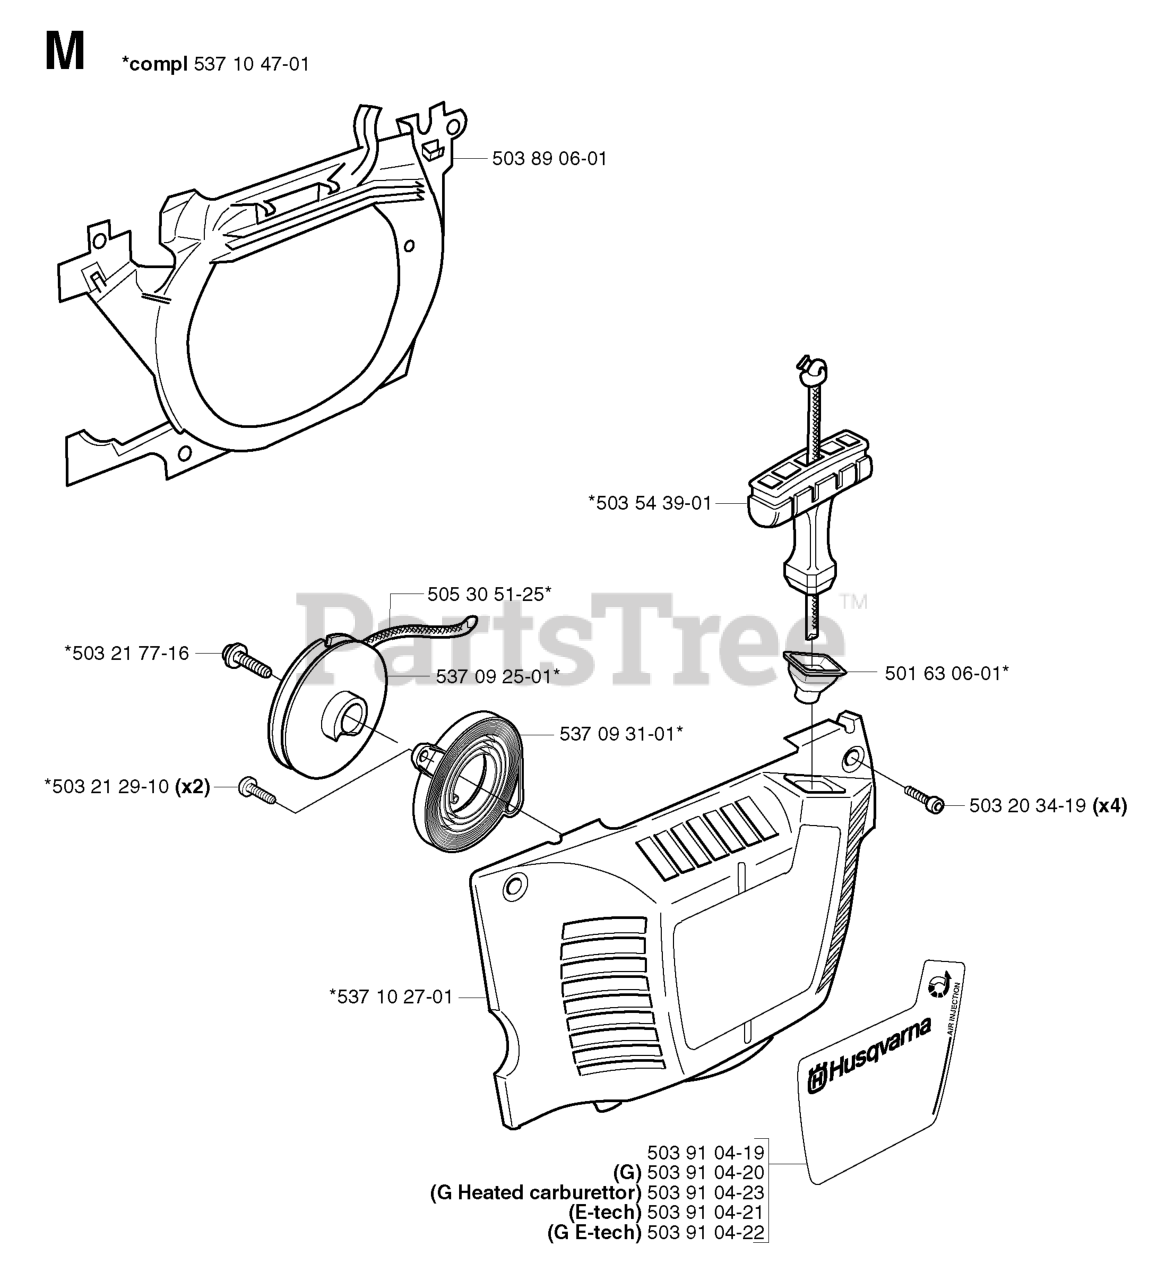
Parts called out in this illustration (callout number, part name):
3	APPLIQUE.SUBASM.GT.HUSQ.II
5	UPPER.GT2.SVC.MINDING.C-O.M;H
14	HOOD.ASM.HUSQVARNA.GT.TEX.ORAN
15	LENS.HEADLIGHT.LH.GTII.2011
18	GRILLE.SUBSTRATE.2011.
25	LENS.HEADLIGHT.RH.GTII.2011
34	PLATE.ENGINE.WELDED.CHASSIS
36	SCREW 5/16"
37	FENDER.TLT.PDL.CNTRL.W/CPH.ORG
52	LOCKNUT
68	Screw 5/16-18 x 1/2 Hex, Self Tapping 5/16-18 x 1/2
125	CLIP.FUEL.LINE
130	SCREW.#10 X 0.750.BOS
137	BUMPER DASH
138	HOLDER.CUP.LT.GREY
146	BOLT.RDHD.SHT.SQNK.3/8-16X5/8
150	AIR.DUCT.GTV2(2.54"RING HEIGHT
151	BRACKET.PIVOT.HOOD.GT.HUSQ.II
152	SHIELD.BROWNING.PNT.GT.V2
159	SCREW, 3/8-16X3/4
162	SCREW.HI-LO.CONSOLE
175	PLATE.CROSSMEMBER.HUSQ
176	SCREW.#10-24X5/8.RN.QU
177	BUSHING STEERING
180	CHASSIS
181	BUSHING.MNT.FEND.CRGO.TEX.49
182	DASH LOWER.HUSQ.PRED NO CRUISE
183	BOLT.5/16-18X1-1/4 FULL THD
189	SCREW
191	INSERT.REFLECTIVE.RH.HUSQ.GTII
194	NUT LOCK HEX FLANGE 5/16-18
195	PLUG.HOLE.DASH.LOWER.12V.BLK
196	DECKLFT.CONSOL FULL ASSM GREY
202	VENT.SIDE.RH.GT.HUSQ.II.
203	VENT.SIDE.LH.GT.HUSQ.II.498
204	VENT.TOP.HUSQ.GT2
205	SIDE.TRIM.RH.GT.HUSQ.II
206	SIDE.TRIM.LH.GT.HUSQ.II.GRAY
207	BEZEL LIGHT.RH.GT.II.MYLAR
208	BEZEL LIGHT.LH.GT.II.MYLAR
213	BOLT
214	CLIP.RETAINER.TINNER.
217	ROD.PIVOT.HOOD
218	X-PIECE.HOOD.STOP.NON/
228	STUD.FASTNER.W/ANTI-ROTATE
235	SPACER FENDER
236	NUT.CENTERLOCK.5/16-
287	SCREW 1/4X20
297	INSERT.REFLECTIVE.LH.HUSQ.GTII
306	NUT LOCK FLG 3/8-16 UNC
335	COVER.LOWER.DASH.RH.BLACK
336	COVER-LH.LOWER.DASH.GT2.BLACK
350	CLIP.X-MAS.TREE
375	BUMPER CLIP-ON. DASH 1"
